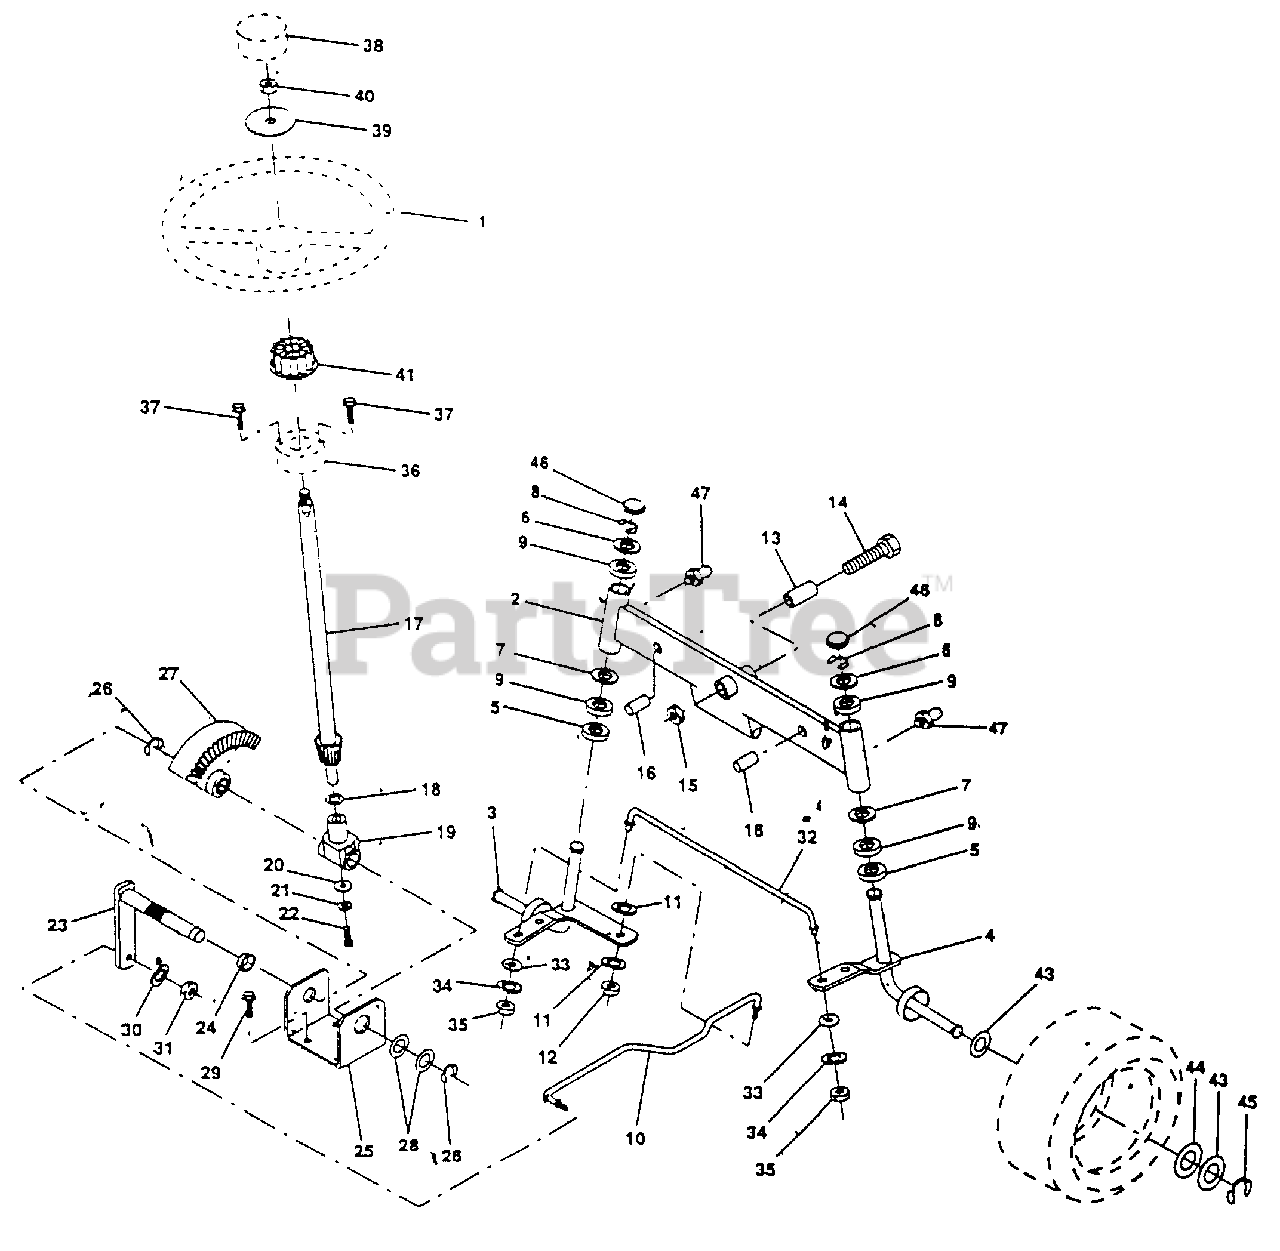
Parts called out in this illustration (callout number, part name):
1	Wheel Steering Auto Grey
2	Axle Asm Fr LT W/gzks 38/42
3	Spindle Asm LH
4	Spindle Asm RH
5	Bearing Race Thrust Harden
6	Washer 25/32 X 1-5/8 X 16 Ga
7	Washer 27/32 X 1-1/4 X 16 Ga
8	Ring Klip #t5304-75
9	Bearing Col Strg Blk
10	Link Drag Sol Ball Jt 20 064
11	Washer Lock Hvy Hlcl Spr 3/8
12	Nut Fin Hex 3/8-24 Unf
13	Spacer Bearing Axle Front
14	Bolt Hex 5/8-11 Unc X 3-1/2
15	Nut Lock Flange 5/8-11 Unc
16	Pin Axle 5/8 X 1 55/1 54 Lg
17	Shaft Asm Strg 20 31 x 3/4 YP YT
18	Washer Thrust 515x 750x 033
19	Support Shaft
20	Washer Shim 1/4 X 5/8 X 062
21	Washer Lock Hvy Helical 1/4
22	Screw Hex Socket 1/4-20 X 5/8
23	Shaft Asm Pittman
24	Nyliner Snap In
25	Bracket Steering
26	Ring Klip #t5304-75
27	Gear Sector
28	Bearing Race Thrust Harden
29	Screw Thdrol 3/8-16x3/4 Ty-tt
30	Washer Lock Hvy Hlcl Spr 3/8
31	Nut Fin Hex 3/8-24 Unf
32	Rod Tie Wire Form 19 75 Elec
33	Washer 11/32 x 3/4 x 16 Ga.
34	Washer, Lock Hvy Hlcl Spr 5/16
35	Locknut 5/16-24 Unf
36	Bushing Strg Blk 742/747 Id
37	Screw Slftp #10-16 X 1/2 Ty-b
38	Insert Cap Strg Wh Aut Hus Gry
39	Washer 53 X 2 25 X 160 Zinc
40	Nut Hex Jam Toplock 1/2-20 Unf
41	Adapter Wheel Strg 758/ 753id
43	Washer 25/32 X 1 1/4 X 16 Ga
44	Washer 25/32 X 1-5/8 X 16 Ga
45	Ring Klip #5304-75
46	Cap Spindle Fr Top Blk
47	Fitting Grease
